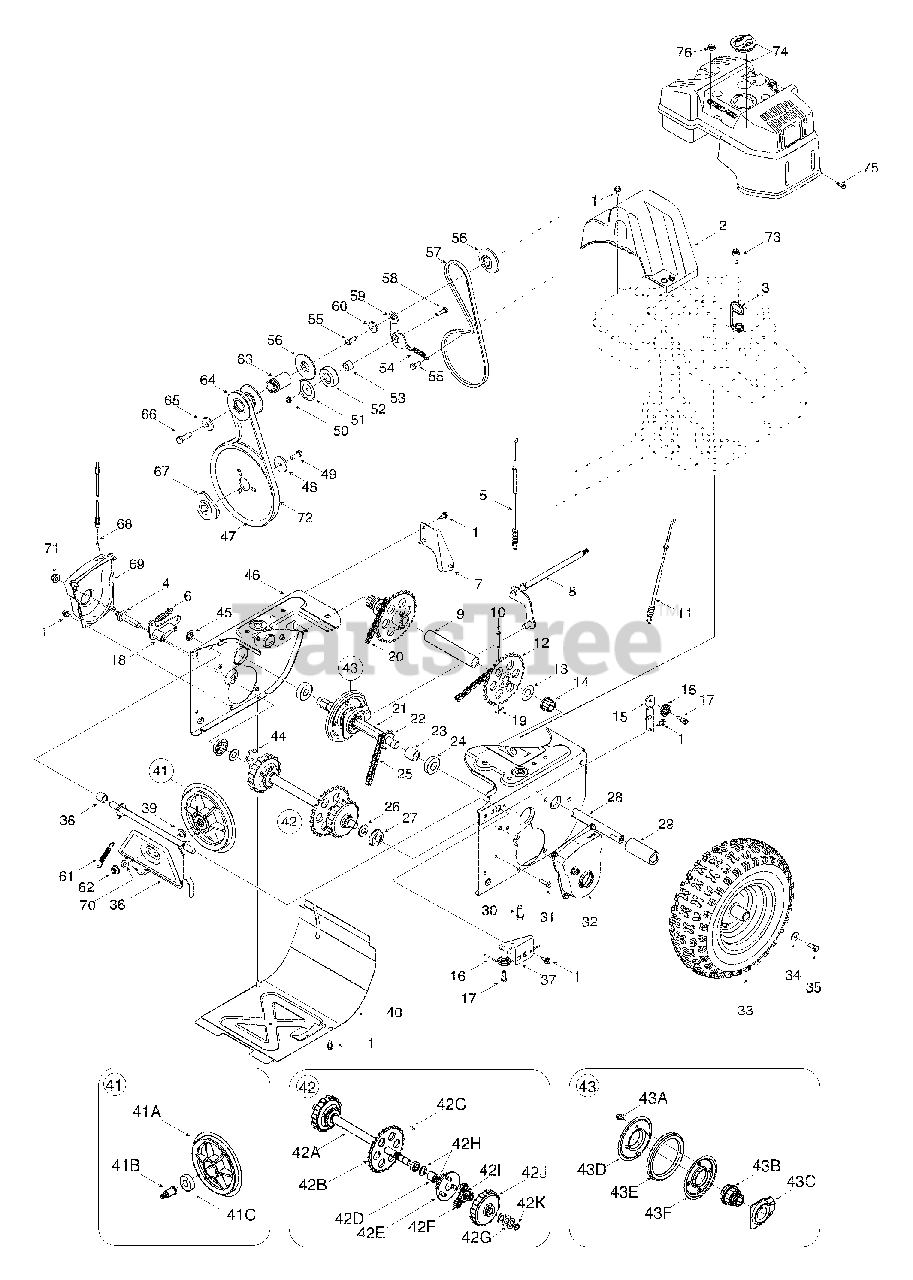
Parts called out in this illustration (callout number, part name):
1	AB Screw, 1/4-20 x 0.625
2	Belt Cover
3	Cable Guide
4	Actuator Shaft
5	Drive Clutch Cable
6	Extension Spring
9	Axle Support Tube
10	Clevis Pin
11	Auger Clutch Cable
12	Sprocket
13	Flat Washer
14	Hex Flange Bearing
17	C Screw, 1/4-28 x 0.375
18	Dogg Assembly - RH
19	Hairpin Clip
21	Drive Shaft
22	Sprocket
24	Ball Bearing
26	Flat Washer
27	Ball Bearing
28	Axle
30	TT Sems Screw, 3/8-16 x 1.0
31	TT Screw, 1/4-20 x 1.0
34	Bell Washer
35	Hex Bolt, 5/16-24 x 0.75
39	Flat Washer
41A	Friction Wheel Disc
41B	Friction Disc Bearing Pin
41C	Ball Bearing
42	Drive Shaft Assembly
42A	Drive Shaft
42B	Sprocket
42E	Planetary Carr. Assembly
42G	Flat Washer
42H	Flat Washer
42J	Planetary Ring Gear
42K	Retainer Ring
43	Friction Wheel Assembly
43A	AB Screw, 1/4-20 x 0.625
43B	Friction Wheel Hub
43C	Bearing Assembly
43D	Friction Plate
43E	Friction Wheel Rubber
43F	Friction Plate
44	Retainer Ring
45	Speed Nut
48	Flat Washer
49	Hex Bolt, 5/16-24 x 0.875
50	Flange Lock Nut, 1/4-20
51	Bearing Washer
52	Ball Bearing
53	Spacer
54	Extension Spring
55	Hex Bolt, 5/16-24 x 0.75
56	Pulley Half
57	V-Belt, 3/8 x 28.6
58	Hex Bolt, 1/4-20 x 1.0
61	Extension Spring
62	Jam Nut, 3/8-24
64	Pulley Half
65	Flat Washer
66	Hex Bolt, 3/8-24 x 1.25
67	Pulley Adapter
68	Steering Cable
69	Shaft Retainer - RH
70	Bell Washer
71	Flange Lock Nut, 3/8-16
72	V-Belt,.500 x 35.00 Lg
73	TT Screw, 5/16-18 x 1.00
74	Engine Shroud
75	Screw, #10-16 x.75
76	Flange Lock Nut, 5/16-18
